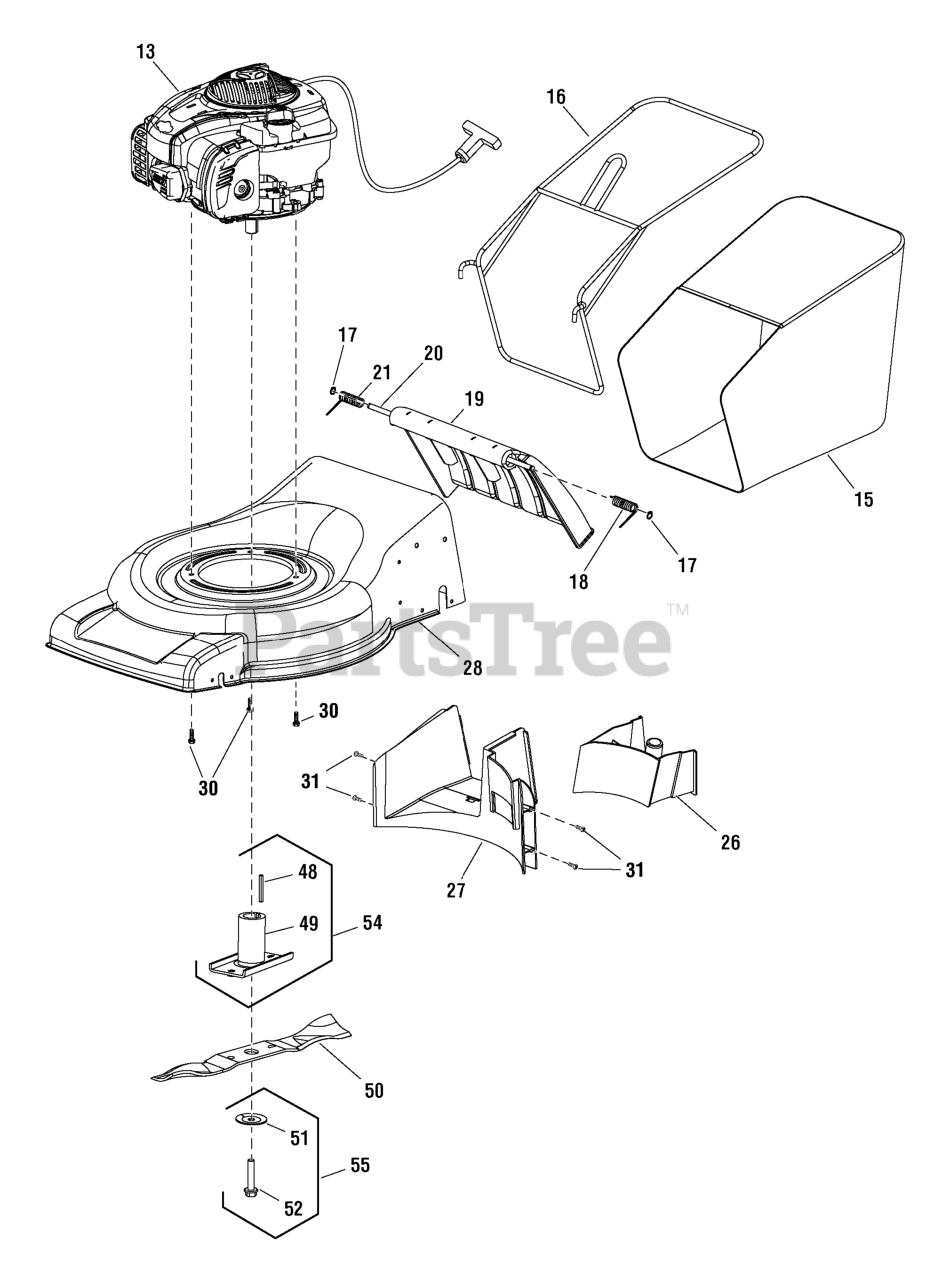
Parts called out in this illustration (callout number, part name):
13	* ENGINE, Briggs & Stratton 550EX Series
15	BAG, Grass
16	FRAME, Grass Bag
17	CIRCLIP
18	SPRING, Left
19	REAR FLAP
21	SPRING, Right
26	MULCH PLUG
27	BAFFLE, Rear
30	BOLT, Self Tapping
31	SCREW, With Washer, ST4.8 x 13
49	ADAPTER, Blade
51	WASHER, Cone
52	BOLT, Blade, 3/8-24 UNF
54	KIT, Blade Adapter
55	KIT, Hardware, Blade Bolt
